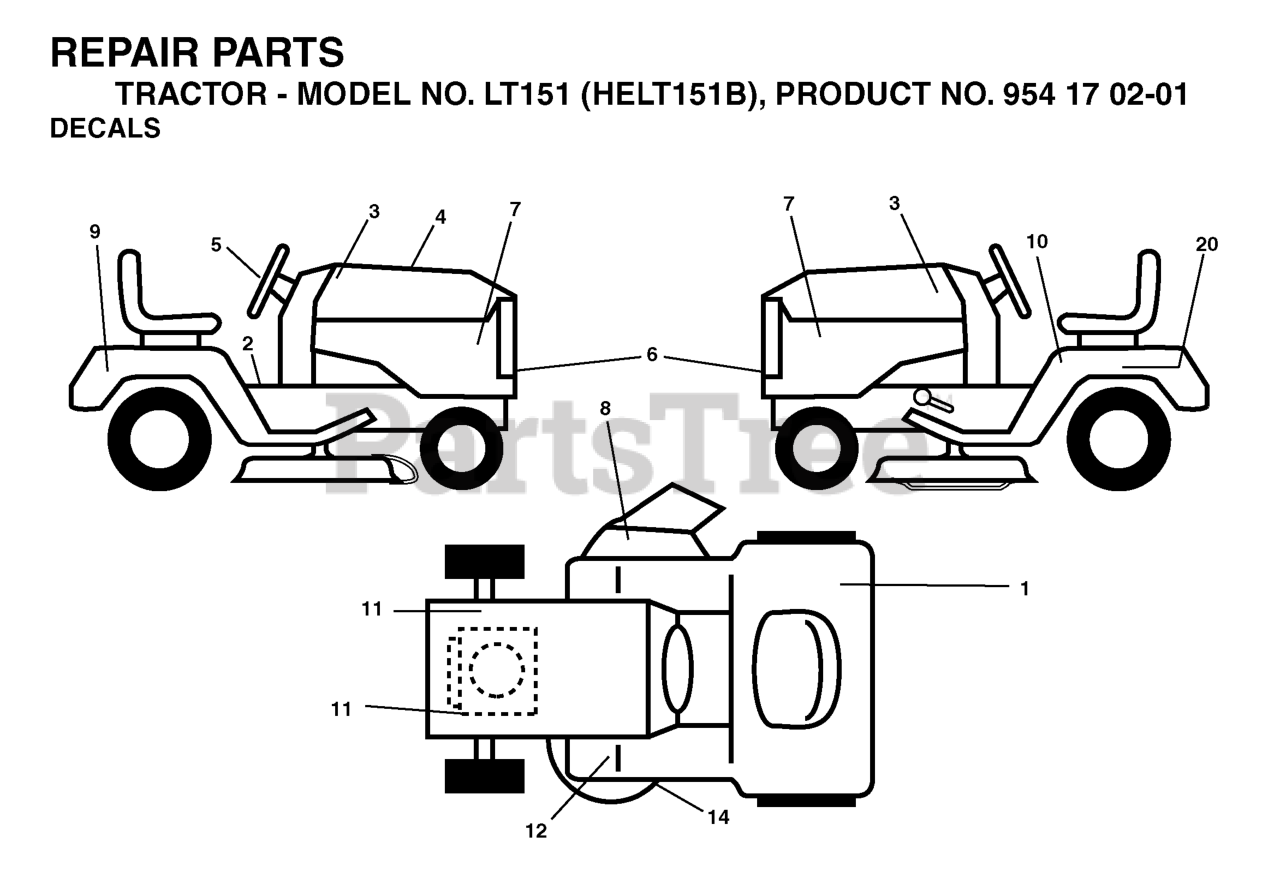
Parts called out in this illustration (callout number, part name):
1	Decal, Fender 100 DB/CE
2	DECAL PARK BRAKE
5	DECAL.STEERING.HUSQ.BLUE
7	DECAL.HOOD.HUSQVARNA.INTERNATI
8	DECAL.INTERNATIONL.CUTFINGER
10	DECAL READ OWNER'S MAN SYMS
12	DECAL
14	DECAL V-BELT SCHEMATIC
20	DECAL BTRY SYMBOLS
